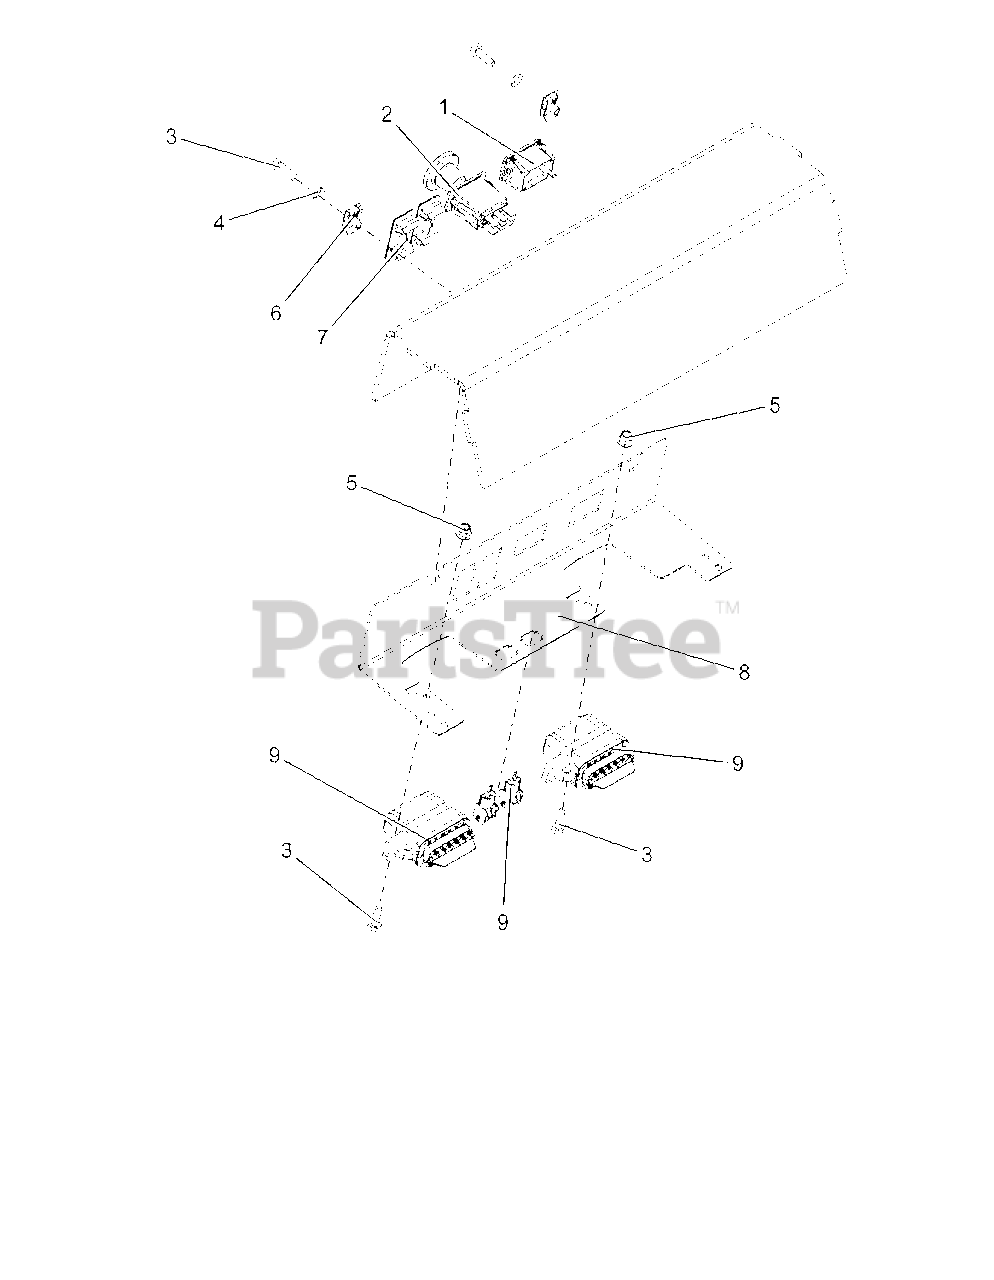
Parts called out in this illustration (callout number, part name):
1	METER, HOUR SMART SENSE W/O SV
2	SWITCH, CLUTCH (WITH GRAPHIC)
3	BLT, HEX M6-1X20 GR8.8 ZC120
4	WSHR-LK .25X.062 REG YWZC
5	NUT, LK-NYL-FLG M6-1.0 GR8.8 ZC120
6	NUT, RTNR M6 X 1.0
7	PLUG, DASH PANEL
8	BRKT, ELEC-RED
9	WIRE, HARNESS RAPID
